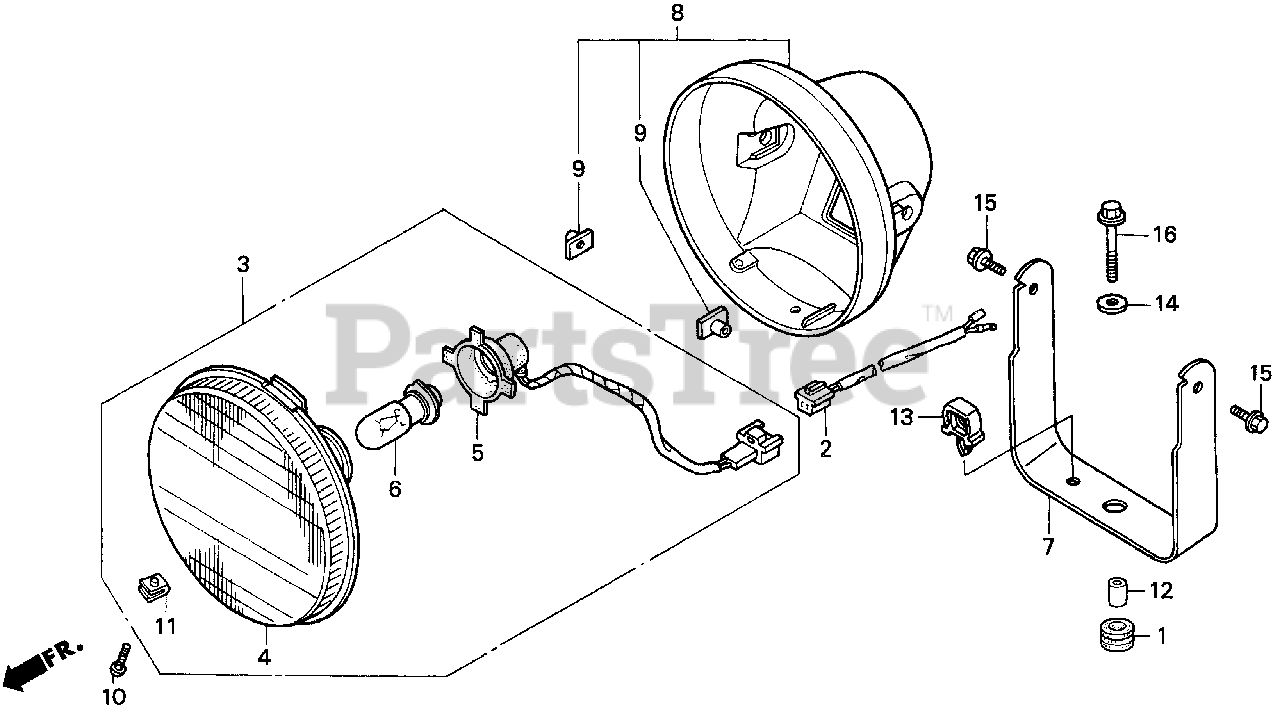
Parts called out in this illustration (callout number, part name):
1	GROMMET, OIL COOLER
2	WIRE ASSY., WORK LIGHT
3	HEADLIGHT ASSY.
4	HEADLIGHT UNIT
5	SOCKET ASSY., HEADLIGHT
6	BULB, HEADLIGHT (12V 15/15W)
7	BRACKET, HEADLIGHT
8	CASE ASSY., HEADLIGHT
9	NUT, SPECIAL (6X7)
10	SCREW, PAN (5X16)
11	NUT, SPRING (5MM)
12	COLLAR, RR. TURN SIGNAL MOUNTING
13	CLIP, WIRE HARNESS
14	WASHER, PLAIN (8MM)
15	BOLT, FLANGE (6X12)
16	BOLT, FLANGE (8X30)
